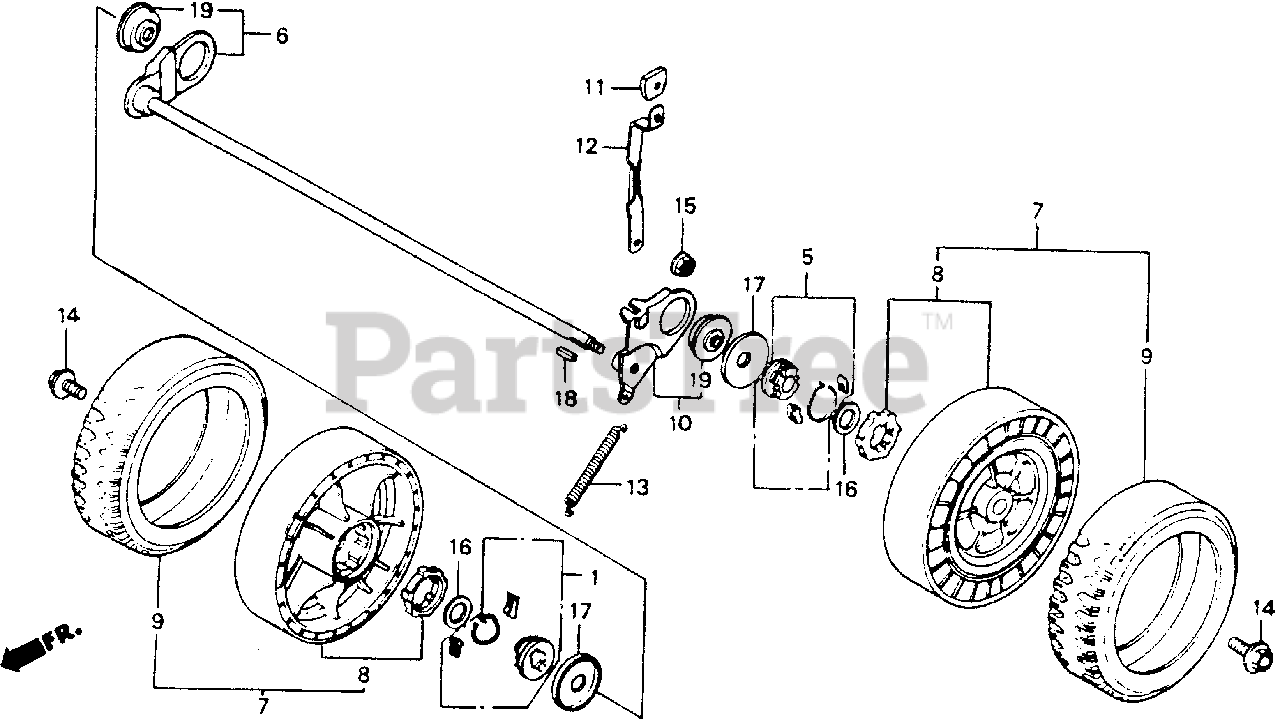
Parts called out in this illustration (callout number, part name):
1	HOLDER, R. RATCHET
5	HOLDER, L. RATCHET
6	SHAFT, RR. AXLE
8	HUB, WHEEL (NA USE ALT:42810-VA3-J00)
9	TIRE (8 INCH)
10	ARM, L. RR. ADJUSTER
11	GRIP, ADJUSTER
12	PLATE, RR. ADJUSTER
13	SPRING, RR. BALANCER
14	BOLT, WHEEL
15	NUT, FLANGE (8MM)
16	WASHER (16MM)
17	WASHER, WHEEL
18	KEY (4X4X11)
19	BEARING, RADIAL BALL
